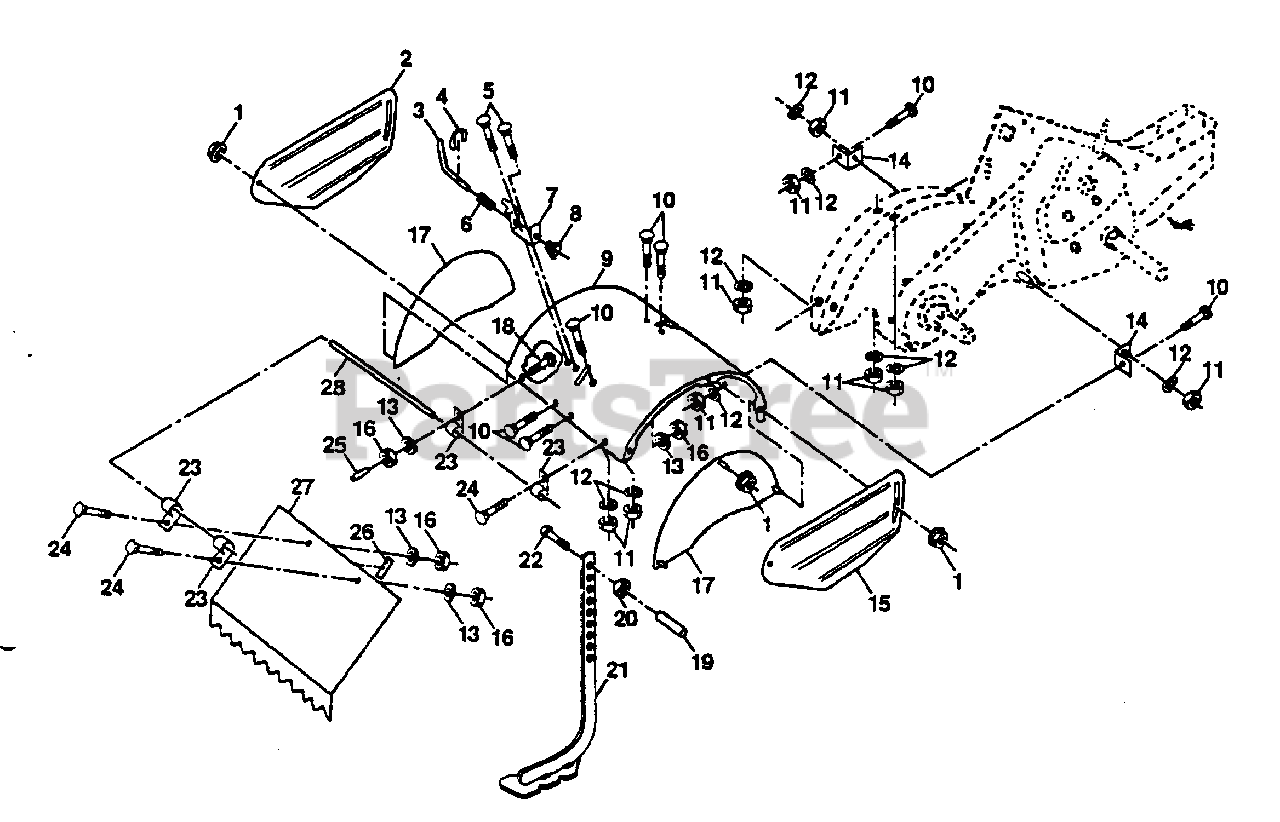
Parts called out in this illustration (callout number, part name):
1	Nut, Flange 5/16-18 (AYP part number)
2	Shield, Side, Outer, L.H. (AYP part number)
3	Pin, Depth Stake (AYP part number)
4	Ring, Klip (AYP part number)
5	Bolt, Carriage 5/16-18 x 1 (AYP part number)
6	Spring (AYP part number)
7	Bracket, Latch (AYP part number)
8	Spring, Depth Stake (AYP part number)
9	Shield, Tine (AYP part number)
10	Bolt, Carriage 5/16-18 x 3/4 Gr. 5
11	Nut, Hex 5/16-18 (AYP part number)
12	Washer, Lock 5/16 (AYP part number)
13	Washer, Lock 1/4 (AYP part number)
14	Bracket, Shield Tine (AYP part number)
15	Shield, Side, Outer R.H. (AYP part number)
16	Nut, Fin, Hex, 1/4-20 (AYP part number)
17	Shield, Side (AYP part number)
18	Bolt, Carriage 1/4-20 x 1-1/4 Gr. 5 (AYP part number)
19	Grip (AYP part number)
20	Nut, Hex 3/8-16 (AYP part number)
21	Stake, Depth (AYP part number)
22	Bolt, Hex 3/8-16 x 3-1/2 (AYP part number)
23	Hinge (AYP part number)
24	Bolt, Carriage 1/4-20 x 1/2 Gr. 5 (AYP part number)
25	Cap, Vinyl (AYP part number)
26	Pad, Idler (AYP part number)
27	Shield, Leveling (AYP part number)
28	Pin, Hinge (AYP part number)
